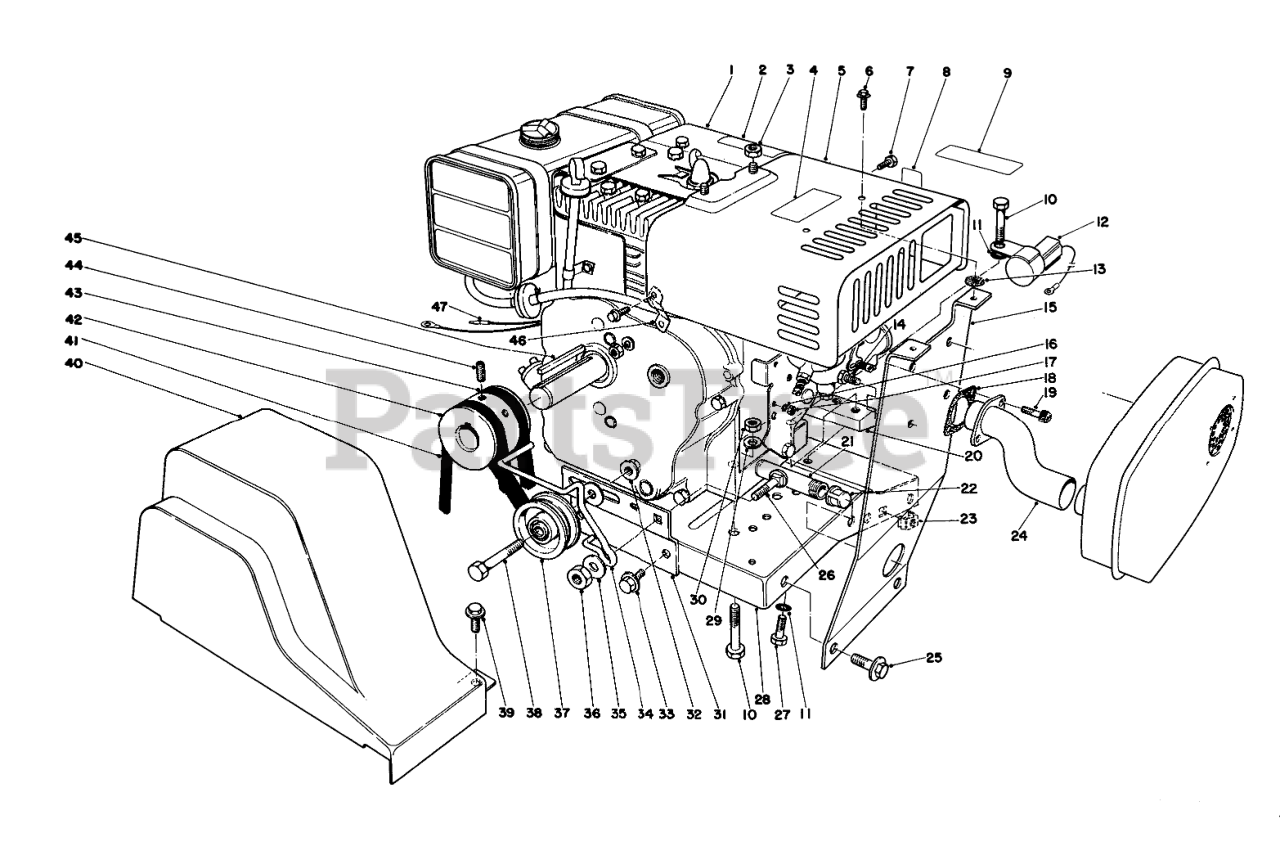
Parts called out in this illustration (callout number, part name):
1	Engine
2	Decal-Hazard
3	NUT-HEX, SIDE DEFORM
4	Decal Hot Surface Warning
5	Heater Box
6	SCREW
8	CHOKE DECAL
9	DECAL SYNCHRO BALANCE
10	SCREW-HH
11	WASHER-LOCK, INTERNAL
12	INTERLOCK MODULE
13	Washer
14	1/4-20 X 1/2 SEMS MS
15	Muffler Mounting Bracket
16	WASHER-LOCK/INT
17	NUT-LOCK
18	Gasket
19	SCREW-HSH
20	Block Engine Mounting
21	NIPPLE-PIPE
22	Pipe Cap
23	Retained Nut
24	EXHAUST PIPE
25	SCREW-HH
26	SCREW-CARR
27	SCREW-HH
28	Engine Base
29	WASHER-PLAIN
30	NUT-LOCK, NI
31	BELT IDLER BRKT
32	NUT-HHF, WHIZ
33	SCREW-HHFTF
34	BELT GUIDE
35	WASHER-FLAT
36	NUT-HEX
37	PULLEY B
38	SCREW-HH
39	SCREW-HWH
40	BELT GUARD
41	V-BELT
42	Pulley
43	V-BELT
44	Screw-Set
46	Brace Heater Box
